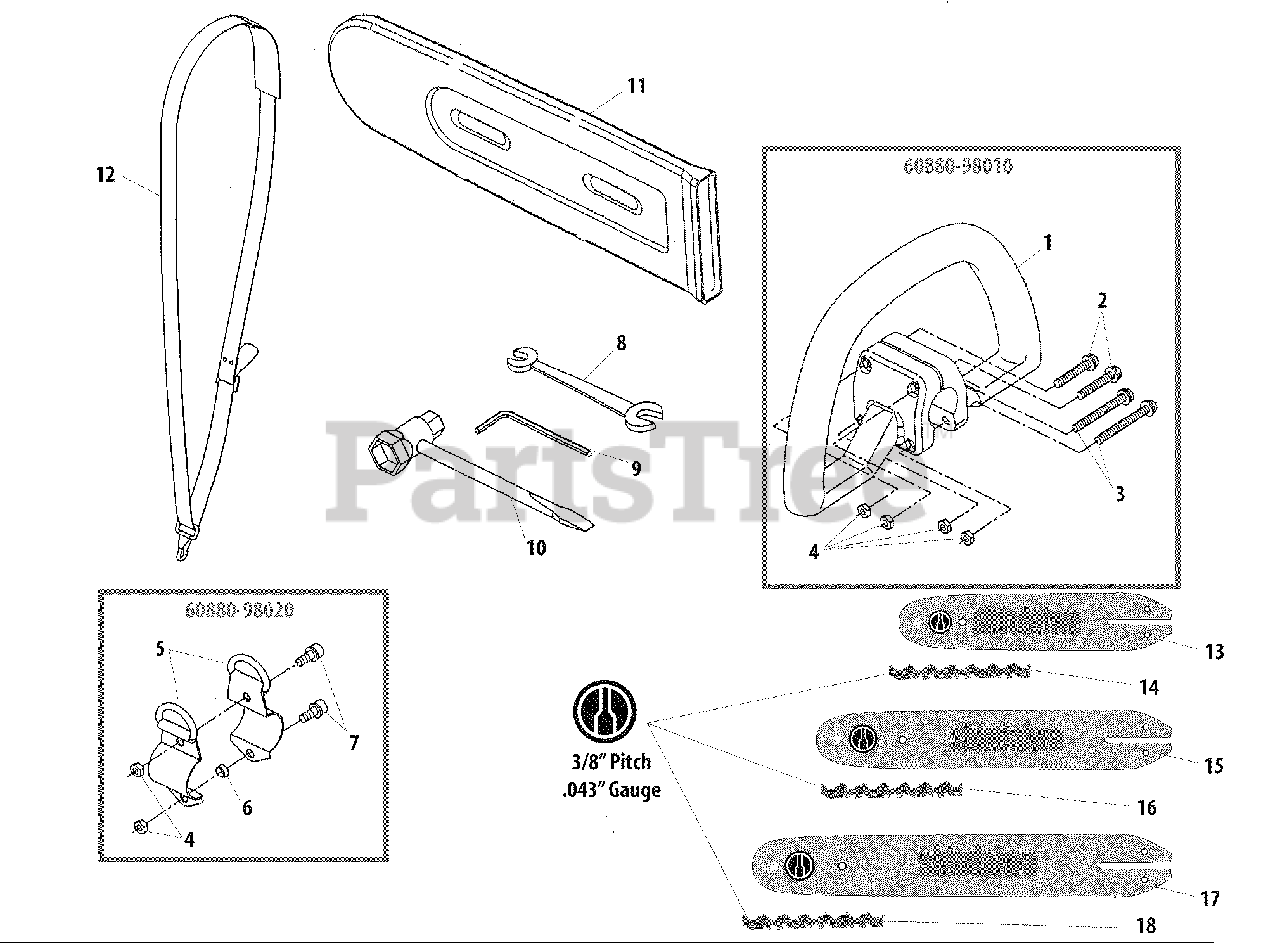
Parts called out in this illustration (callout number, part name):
2	SCREW - 5X30
3	SCREW - 5X45
7	SCREW - 5X12
8	SPANNER - 8X10mm
9	HEX KEY - 4mm
10	T-WRENCH
11	COVER, GUIDE BAR
12	STRAP ASSY
13	GUIDE BAR - 8" (20cm)
15	GUIDE BAR - 10" (25cm)
60880-98010	HANDLE ASSY
60880-98020	HANGER ASSY
